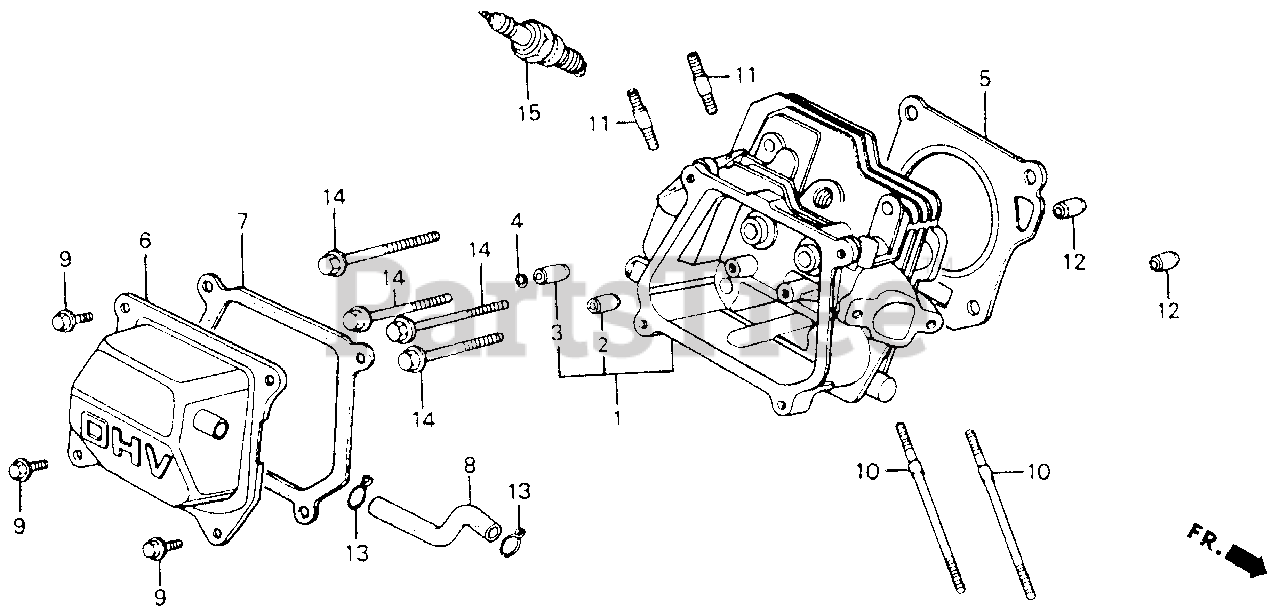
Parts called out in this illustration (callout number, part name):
1	CYLINDER HEAD
2	GUIDE, VALVE (OS)
3	GUIDE, EX. VALVE (OS)
4	CLIP, VALVE GUIDE
5	GASKET, CYLINDER HEAD
6	COVER, HEAD
7	GASKET, CYLINDER HEAD COVER
8	TUBE, BREATHER
9	BOLT, FLANGE (6X12) (CT200)
9	BOLT, FLANGE (6X13)
10	BOLT, STUD (6X112)
10	BOLT, STUD (6X109)
11	BOLT, STUD (8X32)
12	PIN A, DOWEL (10X16)
14	BOLT, FLANGE (8X55)
15	SPARK PLUG (BPR6ES) (NGK)
15	SPARK PLUG (W20EPR-U) (DENSO)
